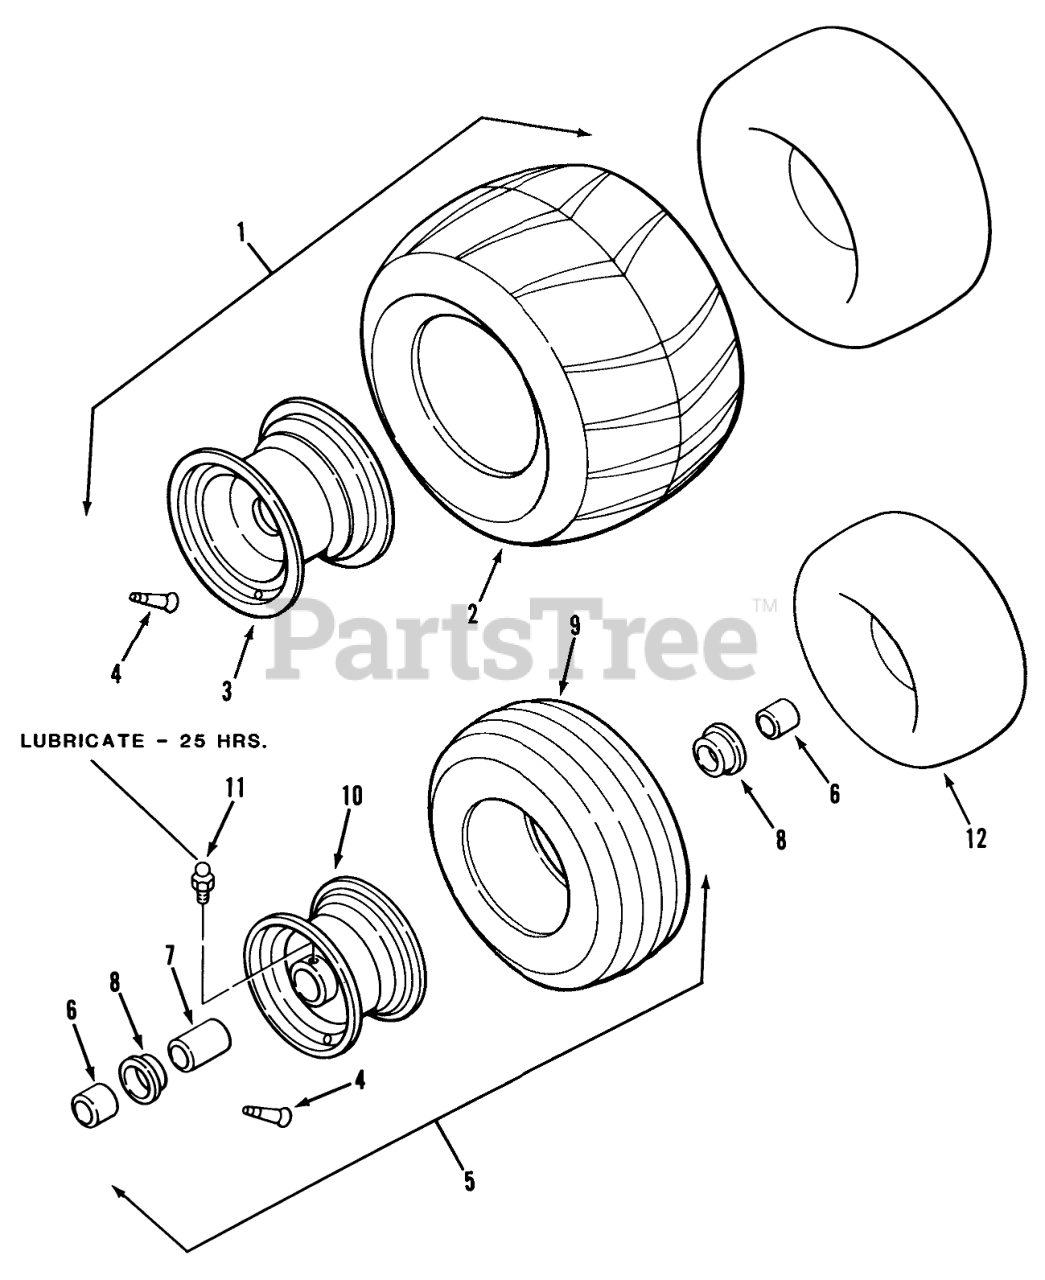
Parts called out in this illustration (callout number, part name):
1	Rear Wheel and Tire 21 x 11.00-8 (Includes items 2, 3, & 4)
2	TIRE 22 X 11.00-8
3	Wheel-Rear, Silver
4	VALVE
5	Front Wheel and Tire Ass-y (Includes items 7, 8, 9 & 10)
6	Tube-Wheel
7	SPACER FRT WHEEL INN
8	BEARING BALL
9	Front Tire 13 x 5.00-6
10	WHEEL FT SLUV 10239K
11	Zerk
12	INNER TUBE
